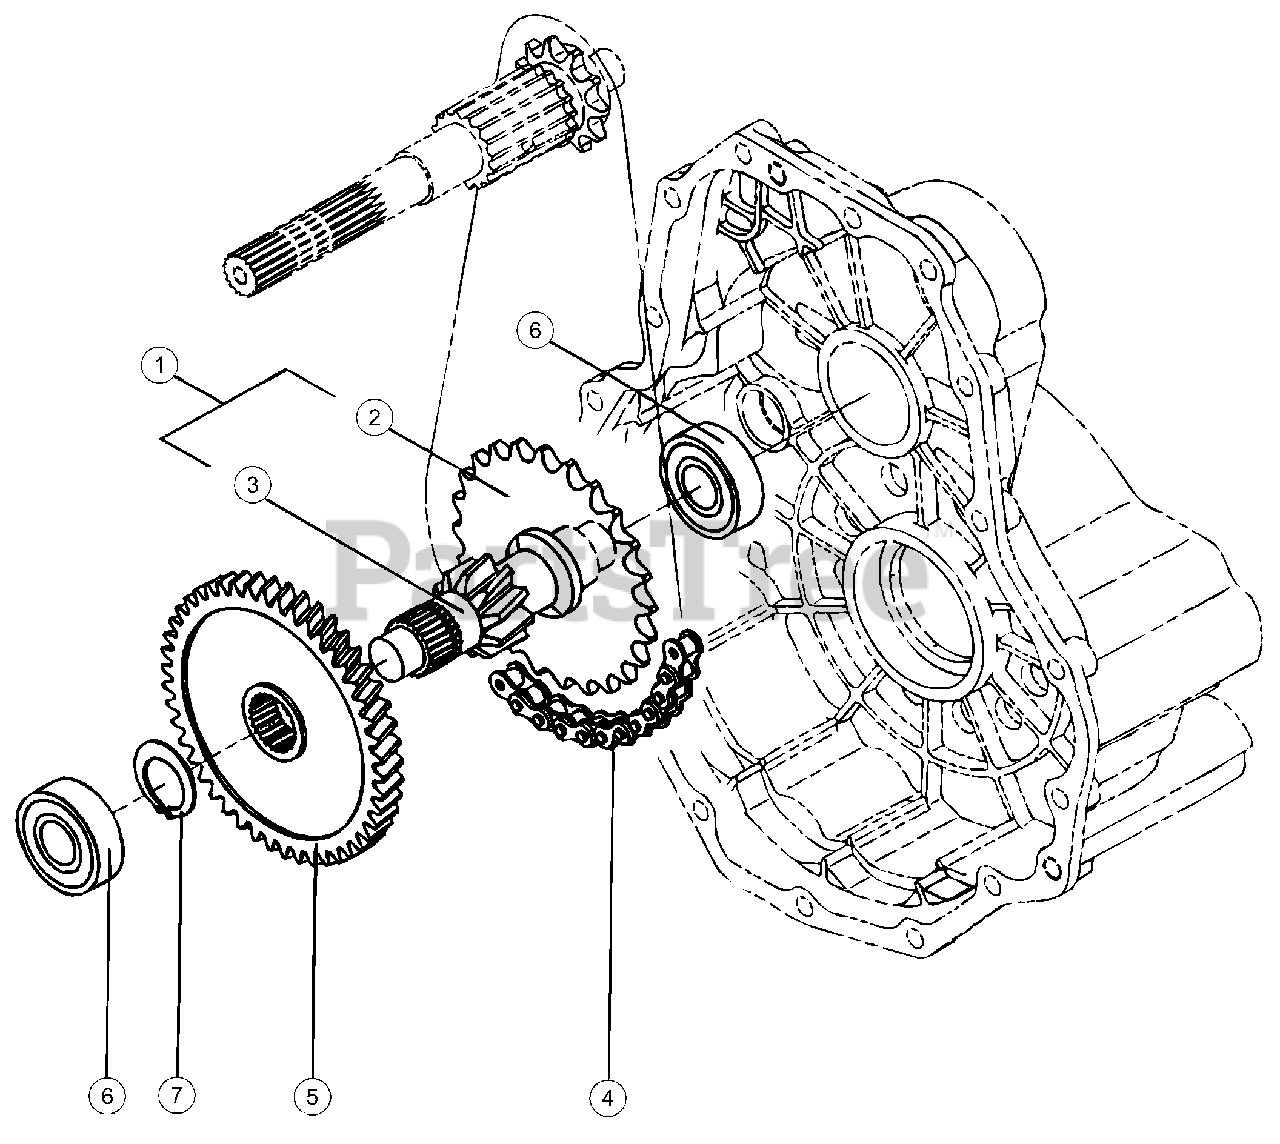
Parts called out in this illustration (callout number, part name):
1	Reduction Shaft Assembly
2	Sprocket, 27
3	Shaft, Reduction
4	Chain, 40 x 34
5	Gear, 46H, Reduction
6	Bearing, 6204R, SH2
7	Ring, 26
